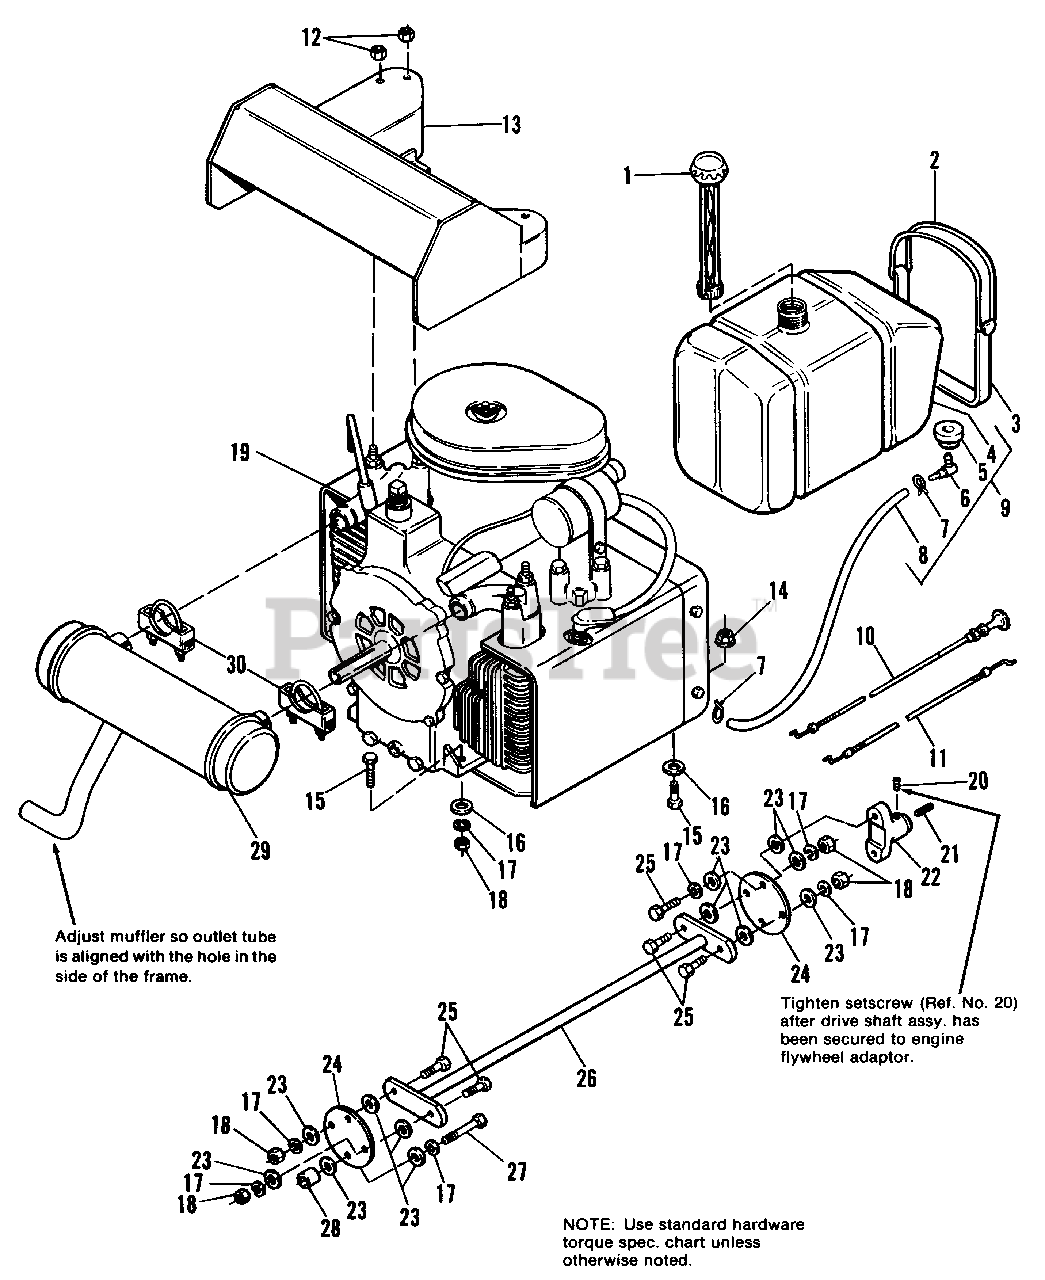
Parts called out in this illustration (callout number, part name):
1	CAP, Fuel Tank, Gauge
2	STRAP, Fuel Tank
3	STRAP, Tank
7	CLAMP, Hose
8	HOSE, Fuel (21-3/4" Long)
9	TANK ASSY., Fuel
10	CONTROL, Choke
11	CONTROL, Throttle
12	LOCKNUT, 2-Way
13	HEAT SHIELD ASSY.
14	LOCKNUT, Hex, Flange, Whiz, 3/8-16
15	CAPSCREW, Hex Hd., 3/8-16 x 1-1/2
16	WASHER, 3/8
17	LOCKWASHER, 3/8
18	NUT, Hex, 3/8-16
19	ENGINE, 17 H.P. Kohler
20	SETSCREW, 3/8-24 x 3/8
21	KEY, Drive Shaft
22	FLANGE, Drive Shaft
23	WASHER, Special
25	CAPSCREW, Hex Hd., 3/8-16 x 1-1/4
26	SHAFT ASSY., Drive
27	CAPSCREW, Hex Hd., 3/8-16 x 2-1/4
29	MUFFLER, Exhaust
30	CLAMP, Exhaust
